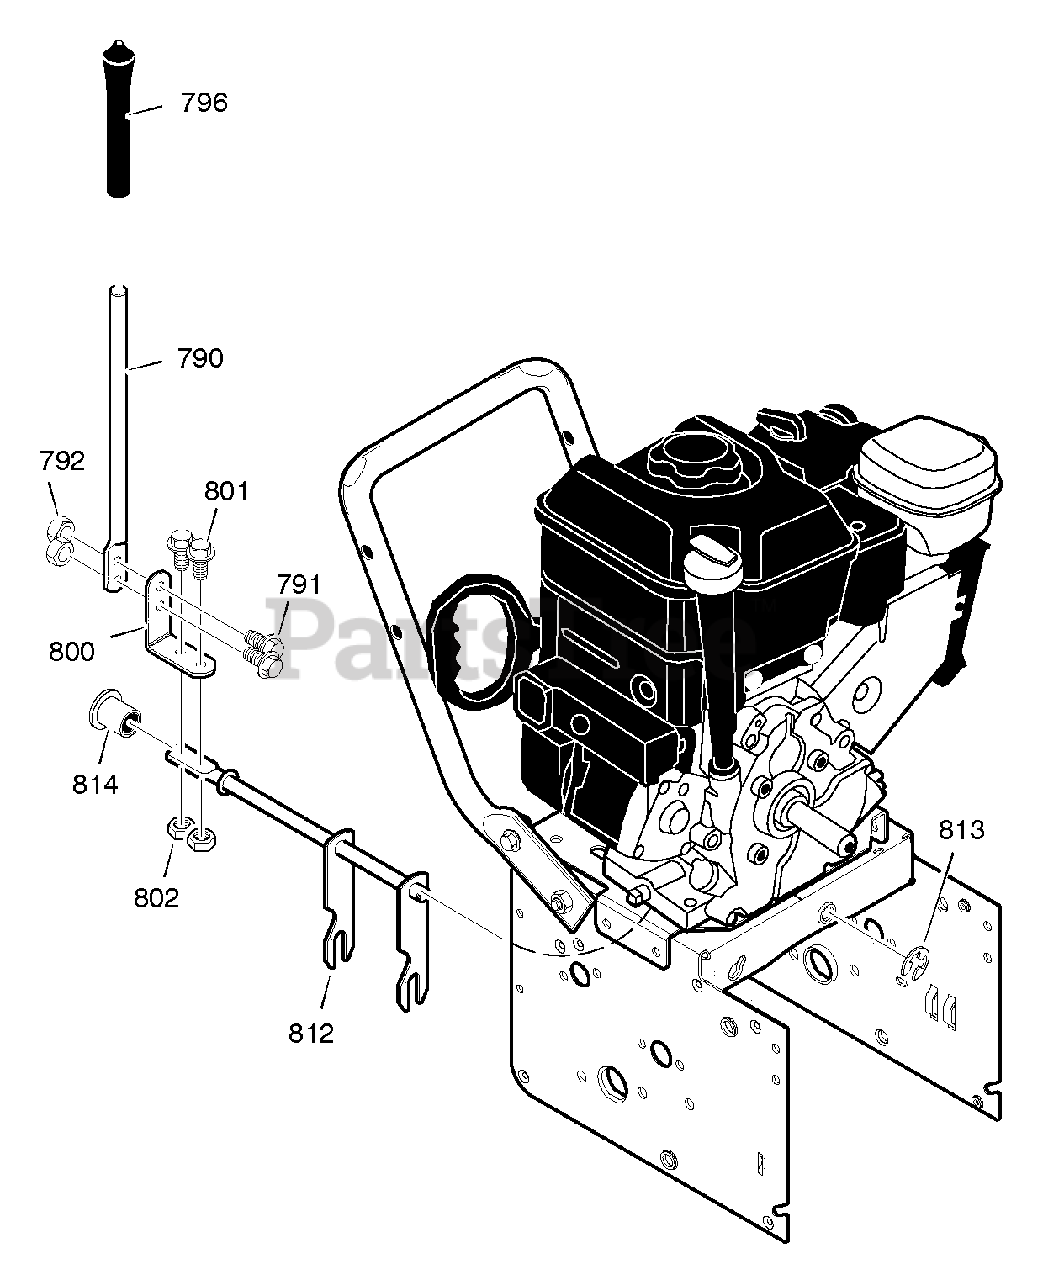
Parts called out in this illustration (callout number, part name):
790	ROD, SHIFT
791	SCREW, 1/4-20X.75
792	NUT, 1/4-20
796	KNOB, SLIP
800	LEVER, SPRING
801	SCREW, 1/4-20X.75
802	NUT, 1/4-20
812	ROD ASSY., SPEED SELECT
813	RETAINER, RING
814	BEARING, FLANGED
